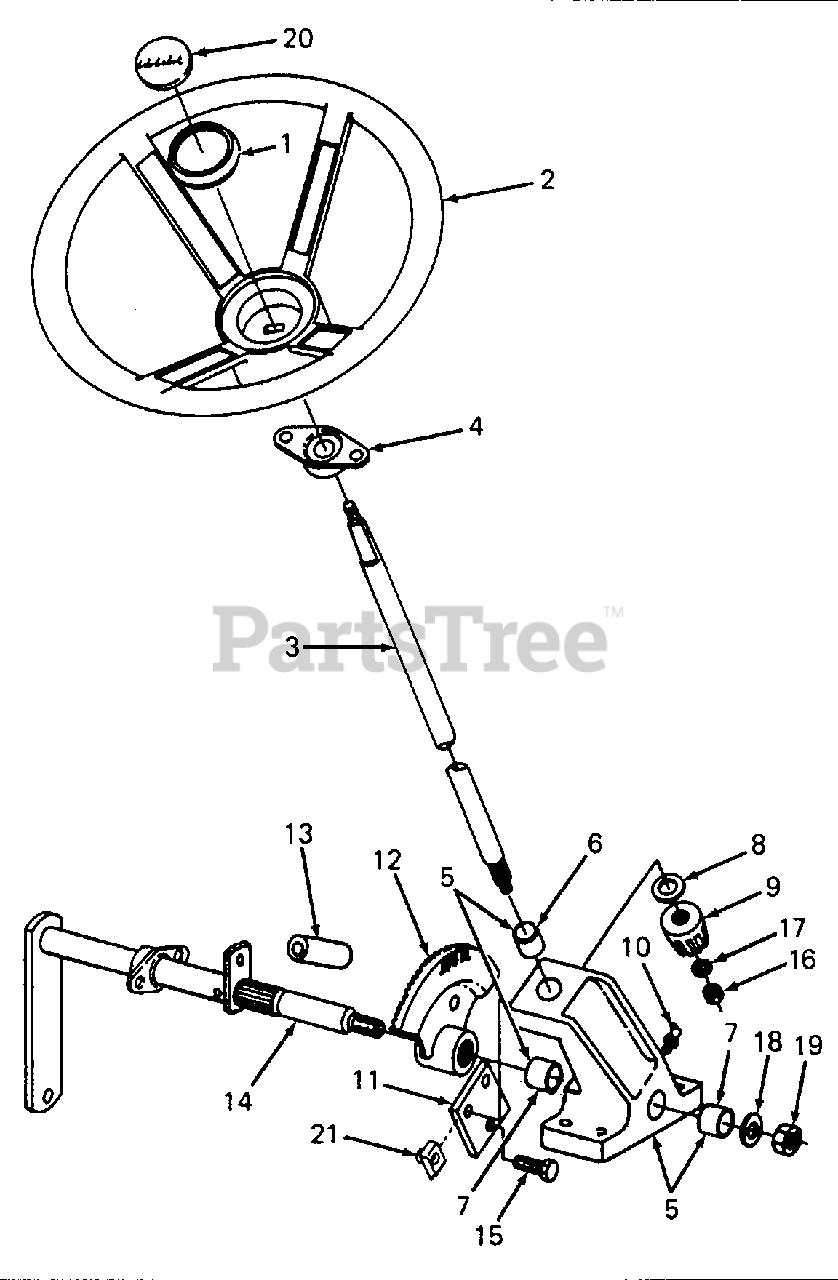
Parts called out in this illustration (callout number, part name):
1	Cap, Steering Wheel
2	Wheel,Steering
3	Shaft, Steering Wheel
4	Bearing, Flange
5	Housing, Steering Gear
6	Bearing
8	Washer, .63 X 1.13 X .09 Hdn
9	Gear, Pinion
10	Fitting, 1/4 45D Taper Drive Thd Lub
11	Plate, Back-Up
12	Gear, Side
14	Shaft, Steering
15	Bolt, Nylon
16	Nut, 5/16-24 Hex Ctr Lock
17	Washer, .344 X .62 X .063
18	Washer, .64 X 1.25 X .100
19	Nut, 1/2-13 Insert Lock
20	Label, Steering Cap
21	Clip, Cable
